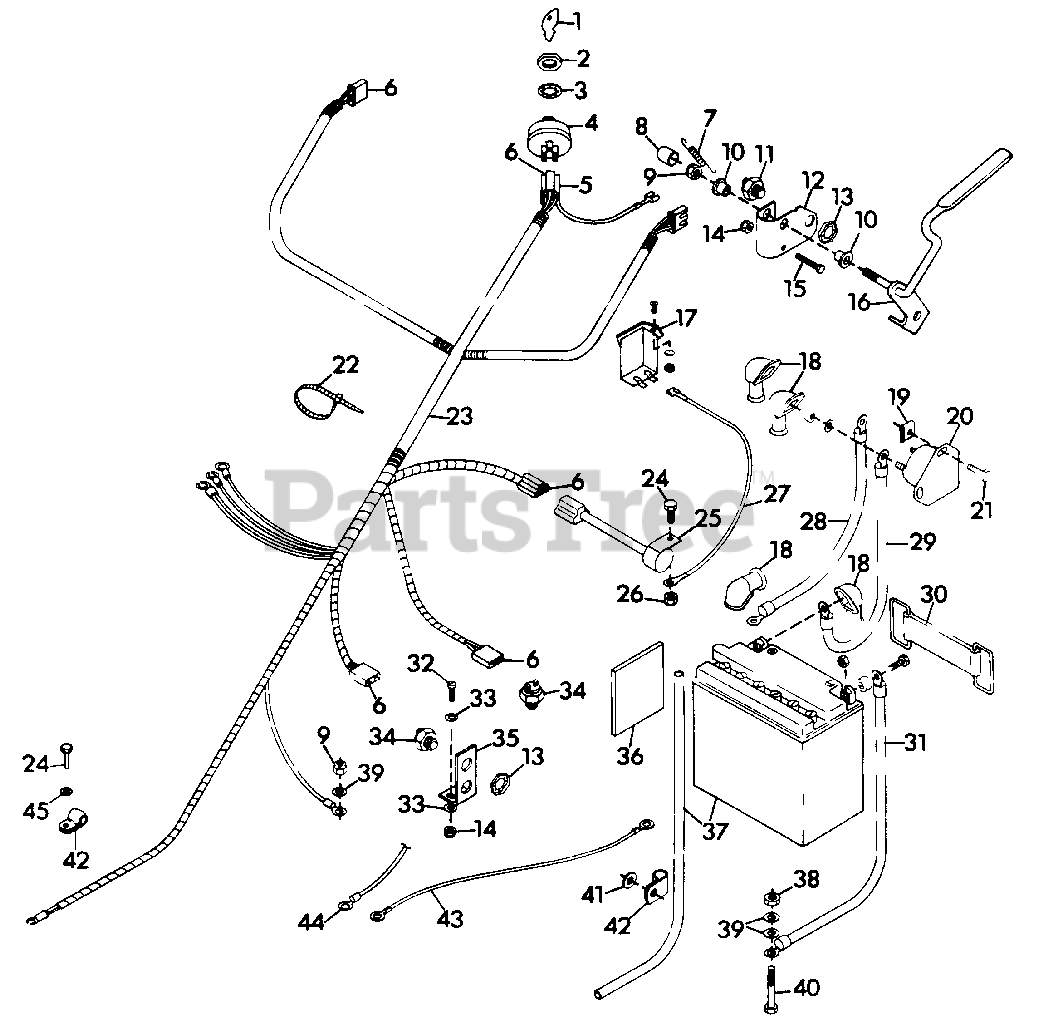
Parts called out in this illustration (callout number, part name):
1	KEY, IGNITION SWITCH
2	NUT, JAM 9/16-24
3	WASHER, LOCK
4	SWITCH, IGNITION
5	CONNECTOR
6	TERMINAL
7	SPRING, INTERLOCK LEVER
8	CLOSURE, VINYL
9	NUT, LOCK 5/16-18
10	BUSHING, INTERLOCK LEVER
11	SWITCH, INTERLOCK
12	BRACKET, INTERLOCK ACTUATING
13	NUT, STAMPED 9/16-18
14	NUT, LOCK 10-24
15	SCREW, MACHINE 10-24X1.50 HEX PHD
16	LEVER, PRESENCE CONTROL
17	HOURMETER
18	BOOT, BATTERY CABLE
19	NUT, SPEED 1/4-20
20	SWITCH, MAGNETIC
21	BOLT, HEX 1/4-20X.750
22	TIE, CABLE
23	HARNESS, WIRING
24	BOLT, HEX 1/4-20X.625
25	MODULE, INTERLOCK ELECTRIC
25	MODULE, INTERLOCK
26	NUT, LOCK 1/4-20
27	WIRE, INSTRUMENT PANEL
28	CABLE, SOLENOID TO STARTER
29	CABLE, BATTERY TO SOLENOID
30	STRAP, BATTERY
31	CABLE, NEGATIVE BATTERY
32	SCREW, MACHINE 10-24X.75 PHD
33	WASHER, FLAT .188X.438X.049
34	SWITCH, NEUTRAL START
35	BRACKET, INTERLOCK SWITCH
36	PAD, BATTERY 3.5X4.0
37	BATTERY, 12 VOLT
38	NUT, HEX 5/16-18
39	WASHER, FLAT .344X.688X.065
40	BOLT, HEX 5/16-18X2.00
42	CLAMP
43	WIRE, GROUND
44	TERMINAL, RING TONGUE
